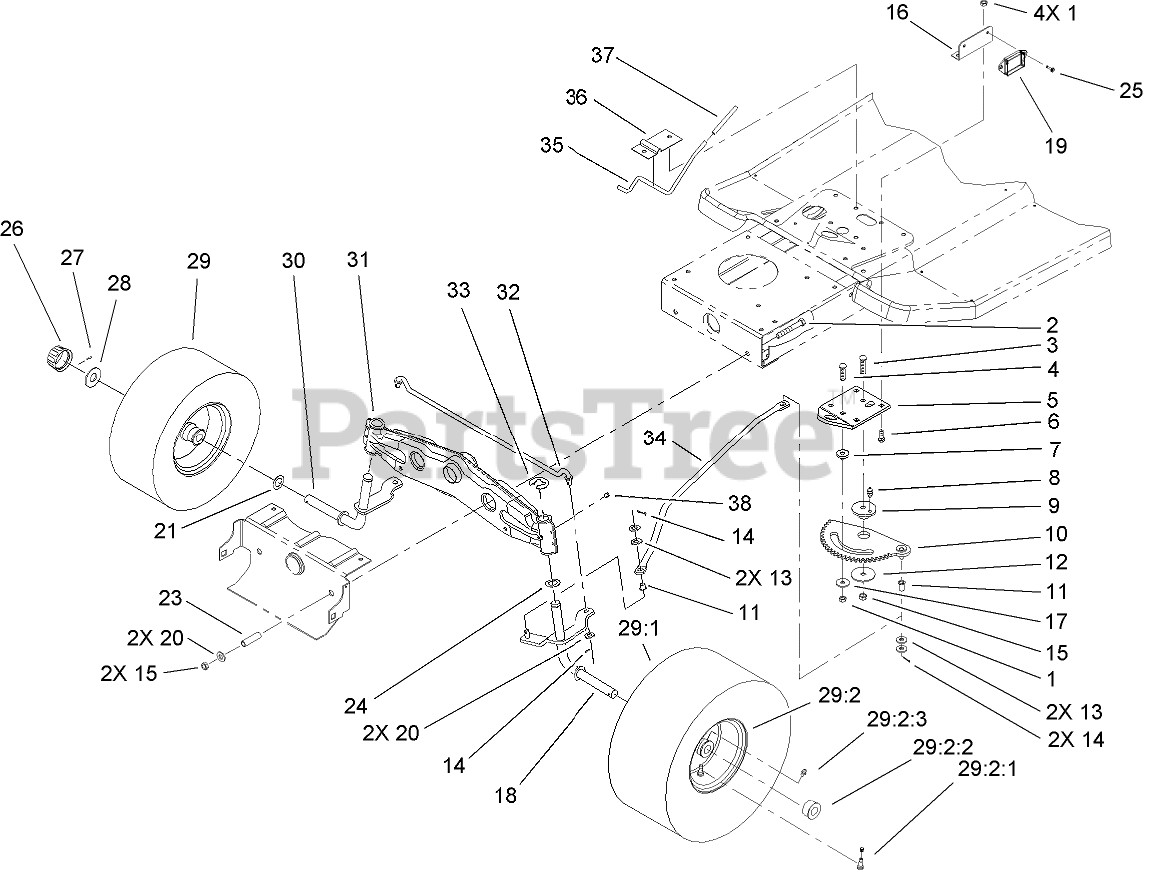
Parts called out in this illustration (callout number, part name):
1	NUT-LOCK, NI
2	SCREW-HH
3	SCREW-CARR
4	SCREW-CARR
5	BRACKET-RACK, STEERING
6	BOLT-CARR
7	SPACER-RACK, STEERING
8	FITTING-GREASE
9	BUSHING-ECCENTRIC
10	RACK-STEERING
11	BUSHING-FLANGED, NYLON
12	WASHER-BEARING
13	WASHER-FLAT
14	PIN-COTTER
15	NUT-LOCK, NI
16	BRACKET-MODULE
17	WASHER-PIVOT
18	LH SPINDLE ASM
19	MODULE-CLUTCH
20	WASHER-FLAT
21	WASHER-THRUST
23	SPACER
24	WASHER-THRUST
25	SCREW-HWH
26	CAP-HUB
27	PIN-COTTER
28	WASHER-PLAIN
29	FRONT WHEEL and TIRE ASM
29:2:1	STEM-VALVE
29:2:2	BEARING-WHEEL
29:2:3	FITTING-GREASE
30	RH SPINDLE ASM
31	AXLE-FRONT
32	TIE ROD-STEERING
33	E-RING
34	LINK-DRAG
35	ROD-BRAKE, PARKING
36	BRACKET-PARKING BRAKE
37	GRIP-BRAKE, PARKING
38	FITTING-GREASE
